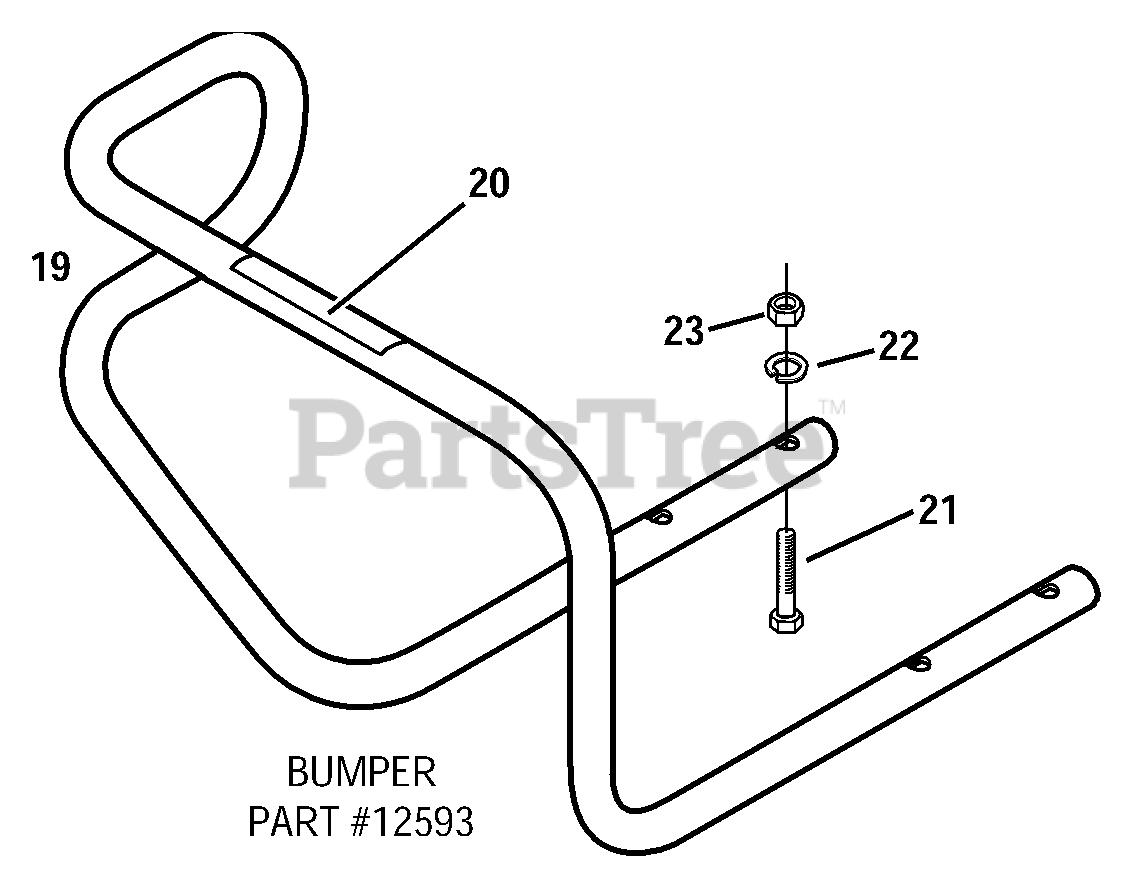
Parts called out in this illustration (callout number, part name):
19	Bumper
20	Decal - Caution
21	Screw-hex hd., 5/16-18 x 2-1/4, not avail. separately (order #1918781 hardware kit)
22	Lockwasher-5/16, not avail. separately (order #1918781 hardware kit)
23	Nut-hex, 5/16-18, not avail. separately (order #1918781 hardware kit)
